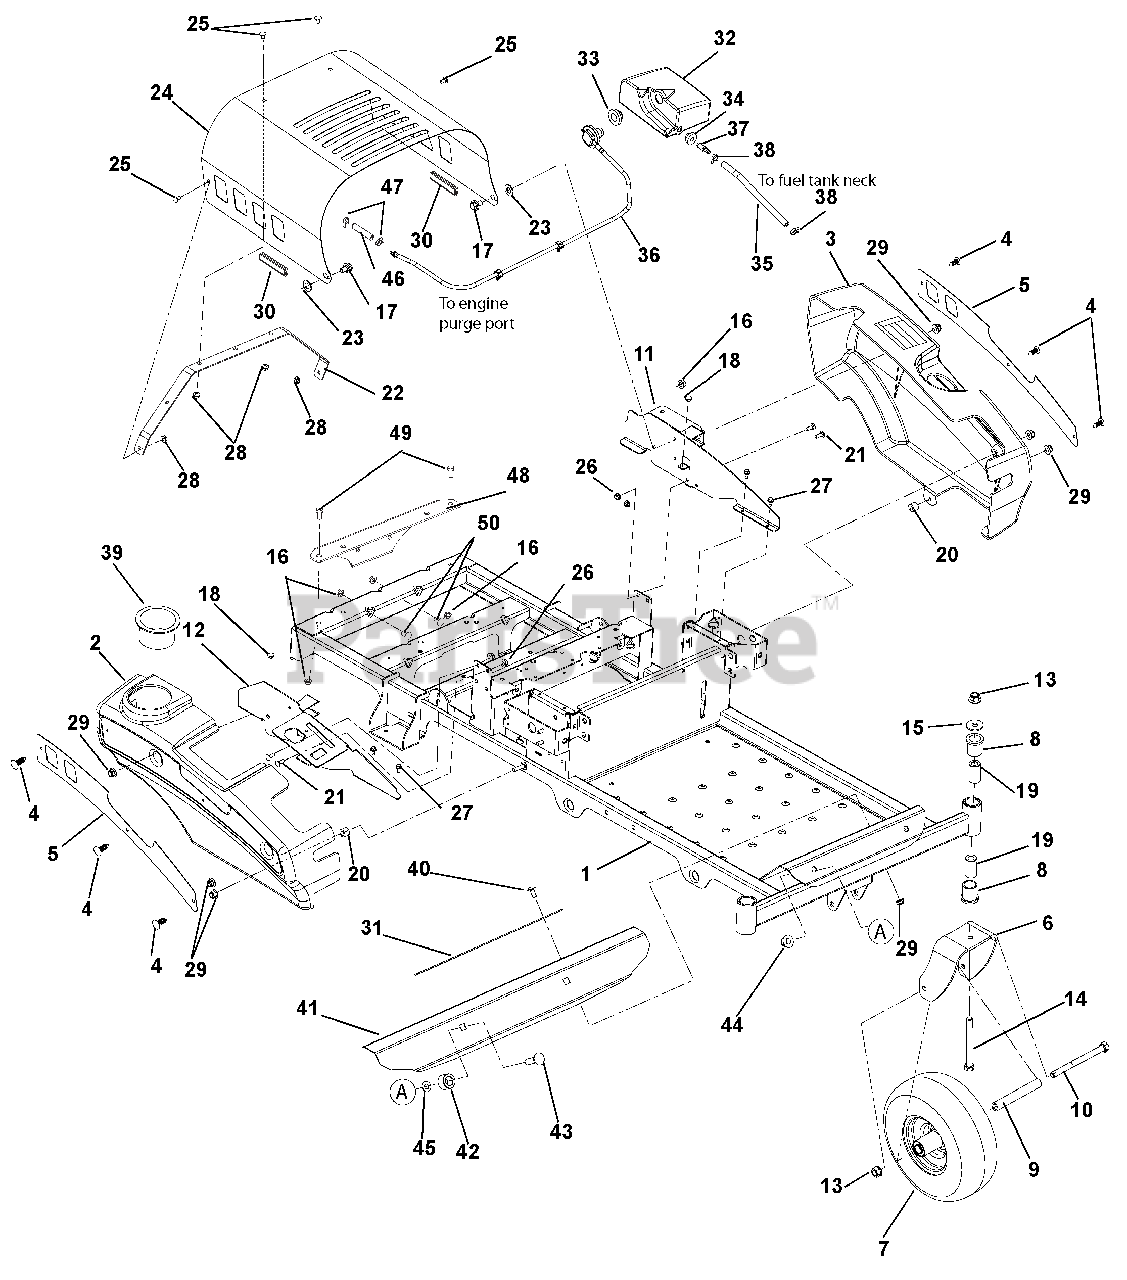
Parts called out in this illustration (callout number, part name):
1	KIT, ZOOM/ZT FRAME W/ DECALS
2	FENDER, RH
3	FENDER, LH
4	RIVET, .25 NYLON PANEL
5	PLATE, FENDER
6	WMT, CASTER FORK
7	TIRE/WHEEL ASSY, 11X4-5
8	BSHG-FLG 1.00X1.25X1.50X1.50
9	SPACER, ROLLED WHEEL
10	@BLT-HEX .50-13X6.50 GR5 YWZC
11	WLDMT, LH FENDER MOUNT
12	WLDMT, RH FENDER MOUNT
13	@NUT-LK-TOP-FLG .50-13 YWZC
14	@BLT-HEX .50-13X5.00 GR5 YWZC
15	WSHR-FL-STL.511X1.441X.125 YWZ
16	@NUT-LK-TOP-FLG .38-16 YWZC
17	BOLT-SHLDR .375-16X.150
18	BUMPER GROMMET
19	SPACER, CASTER .50X1.00X1.84
20	BSHG-SLV .391X.688X.52 PM
21	@BLT-RDHDSQNK .25-20X.75 G5YZ
22	BRACE, HOOD
23	WSHR-FL-NYL .518X1.000X.080
24	HOOD, ZOOM
25	@BLT-RDHDSQNK .25-20X.50 G5YZ
26	@NUT-LK-NYL-FLG .25-20 YWZC
27	@SCR-TAP .25-20X.50 HWH TR YWZ
28	@NUT-LK-TOP-FLG .25-20 YWZC
29	@NUT-LK-NYL-FLG .31-18 YWZC
30	EDGING, CLUTCH PADDLE - 2.00"
31	GRIP, ADHESIVE (1" X 16" BLK)
32	TANK, FUEL EXPANSION
33	GROMMET, REMOTE VENT NITRILE
34	BSHG-FLG .375X1.062X.625 NITR
35	HOSE, .25 LOW-PERM BULK GAS
36	ASM, FUEL VENT - ZOOM/ZT
37	FITTING, STRAIGHT FUEL PLASTIC
38	CLAMP, FUEL LINE
39	CUPHOLDER, SNAP-IN 3.75OD
40	@BLT-RDHDSQNK .31-18X.75 G5YZ
41	FOOTREST
42	TUBE, UPPER CONTROL PIVOT
43	@BLT-RDHDSQNK .50-13X1.75 G5YZ
44	@NUT-LK-NYL-FLG .50-13 YWZC
45	NUT-PUSH, .50
46	HOSE, .188 LOW-PERM BULK GAS
47	CLAMP-HOSE, SPRING .188
48	PLATE, BBZ HITCH KIT PLATE
49	@BLT-HEX .38-16X.75 GR5 YWZC
50	@BLT-RDHDSQNK .38-16X.75 G5YZ
